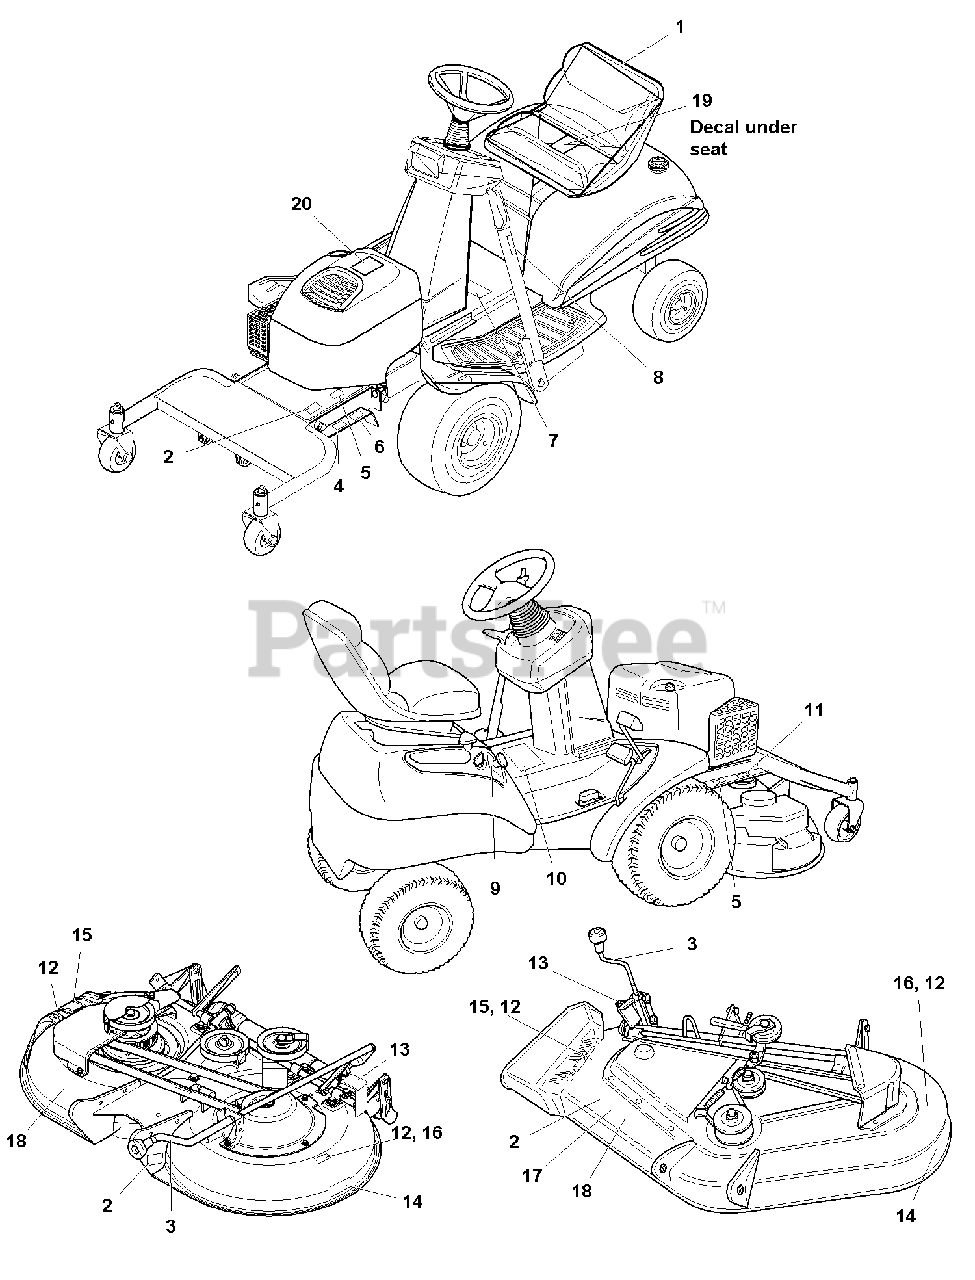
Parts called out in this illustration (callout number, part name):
1	DECAL, USA Logo
2	LABEL, CE & Serial Number, Export (Not Serviced)
2	DECAL, Serial Number (Not Serviced)
3	DECAL, Cutting Height Icons
4	DECAL, Belt Removal
5	DECAL, Warning Shear Point (Export Only)
6	DECAL, Patent (Not Serviced)
7	DECAL, Transmission Release Valve
8	DECAL, Lift Lever Symbols
9	DECAL, Ignition Switch
10	DECAL, Operating Instructions, Icons (Export Only)
10	DECAL, Operating Instructions,
11	DECAL, Caution, Read Manual
12	DECAL, Danger Rotating Blades
13	DECAL, Height of Cut
13	DECAL, Height of Cut, 40" (Export)
14	DECAL, Free Floating
15	DECAL, Danger, Do Not Operate W/O Deflector
16	DECAL, Danger Rotating Blades
18	DECAL, OPEI, (Not Serviced)
19	DECAL, Belt & Blade, 56 Tooth
19	DECAL, Belt & Blade, 38 Tooth
20	DECAL, 17 HP Intek, Briggs & Stratton
